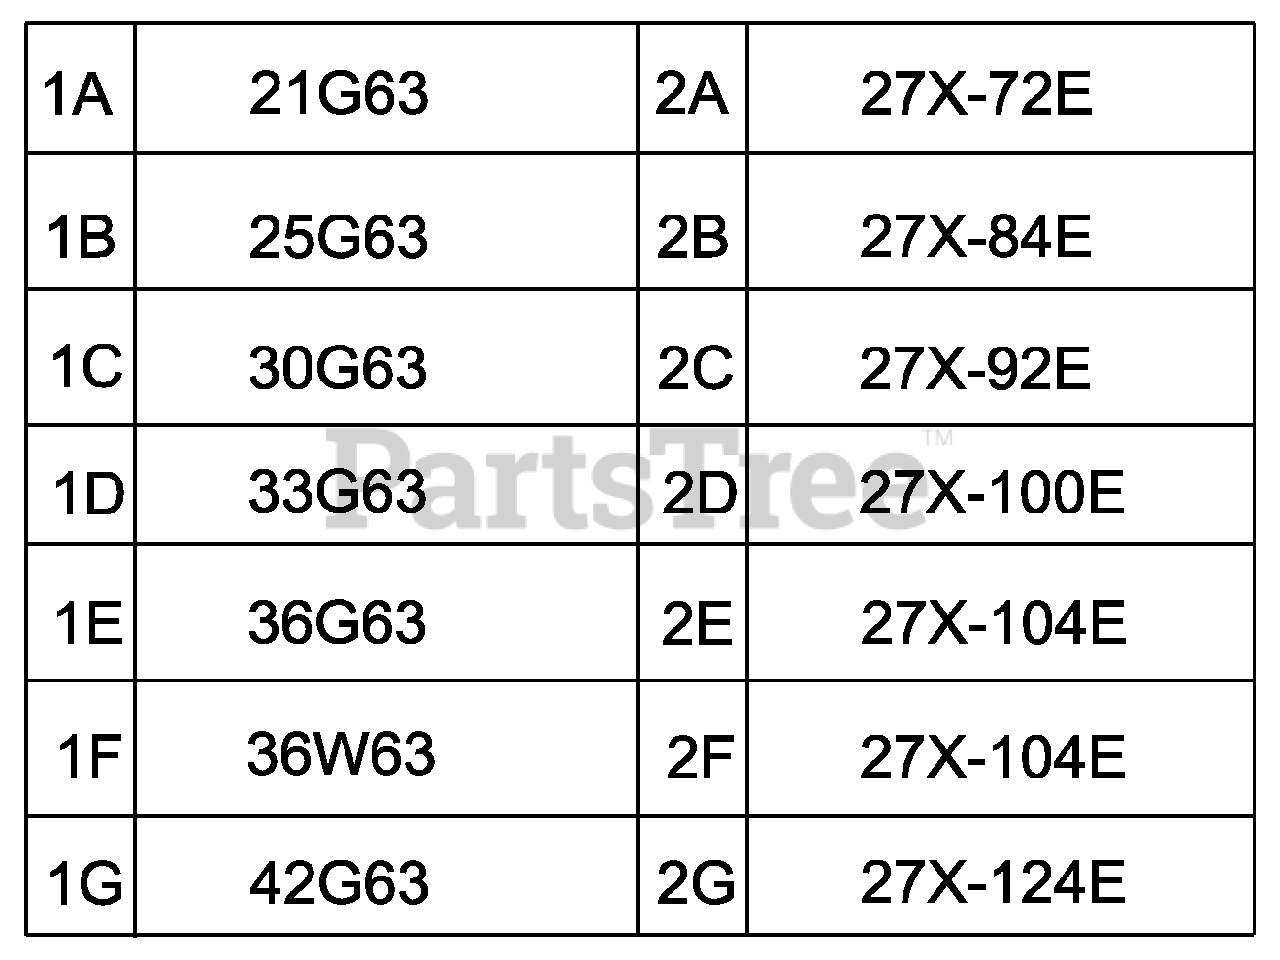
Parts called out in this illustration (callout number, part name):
1A	IDE BAR 21G63
1B	GUIDE BAR - 25" (64 CM)
1C	GUIDE BAR - 30" (76 CM)
1D	GUIDE BAR - 33" (84 CM)
1E	GUIDE BAR - 36" (91 CM)
1F	BAR, 36G63 FOR S.A.
1G	GUIDE BAR
2A	SAWING CHAIN -- 27×-72E
2B	SAWING CHAIN -- 27×-84E
2C	SAWING CHAIN -- 27×-92E
2D	SAWING CHAIN -- 27×-100E
2E	SAWING CHAIN -- 27×-104E
2F	SAWING CHAIN -- 27×-104E
2G	SAWING CHAIN -- 27×-124E
